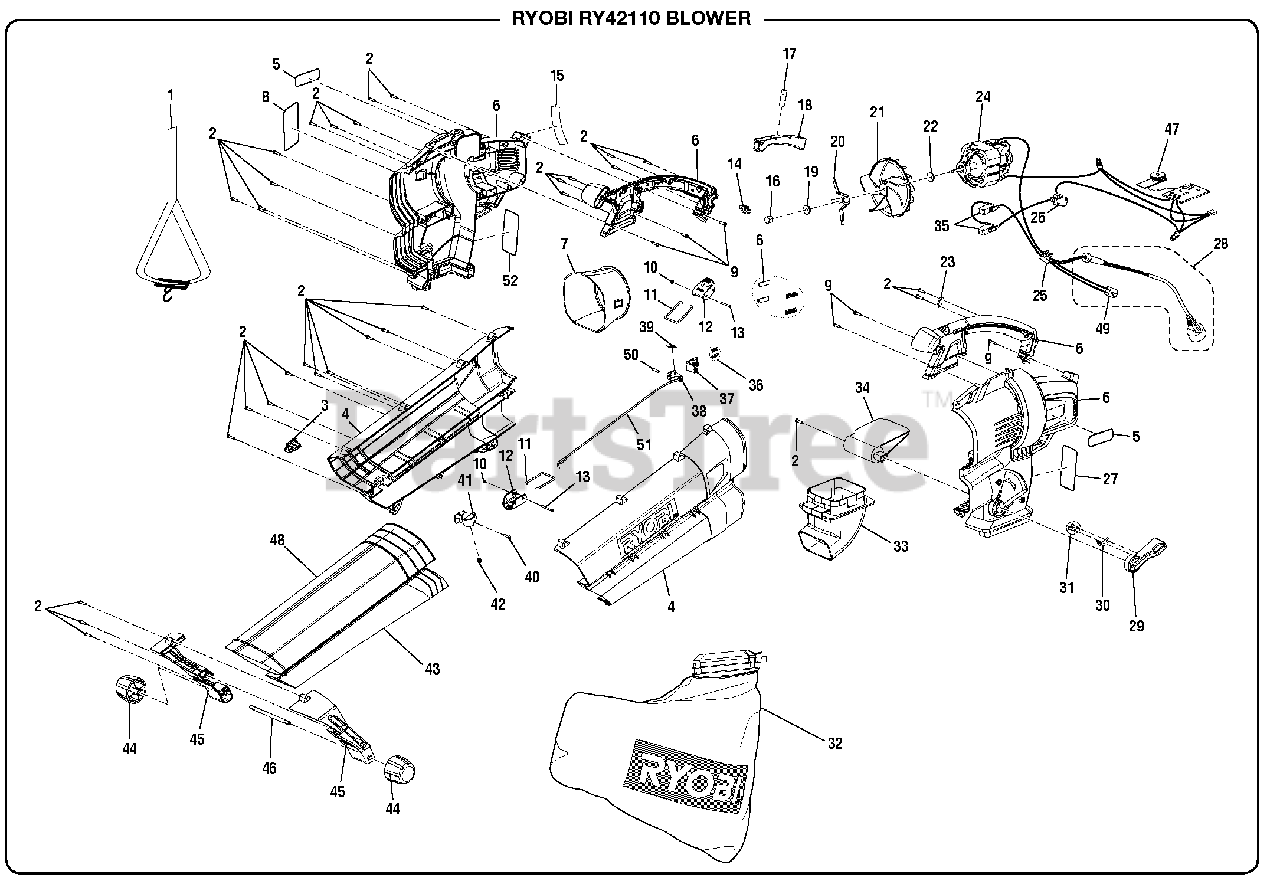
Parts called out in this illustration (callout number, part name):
1	Shoulder Strap
2	Screw (M4 x 16 mm)
4	Upper Tube Assembly
5	Logo Label
6	Housing Assembly
7	Inner Tube
8	Impeller Warning Label
9	Screw (M4 x 12 mm)
10	Hex Nut (M3)
13	Bolt (M3 x 30 mm)
14	Indicator Cover
16	Hex Nut (M10)
17	Compression Spring
18	Switch Trigger
20	Mulching Blade
23	Cord Clamp
24	Motor Assembly
25	Terminal Block
27	Warning Label
28	Cord Assembly
29	Quick Change Lever
31	Screw (M4 x 5 mm)
32	Leaf Bag Assembly
33	Discharge Outlet Elbow
34	Air Deflector
35	Micro Switch
36	Block Spring
37	Slide Block
38	Cam Wheel
39	Torsion Spring
40	Screw (M3 x 12 mm)
41	Lock Block
42	Compression Spring
43	Blower Tube
44	Guide Wheel
45	Front Bracket
46	Wheel Axle
47	Circuit Board Assembly
49	Live Tool Indicator
50	Screw (M3 x 12 mm)
51	Steel Wire
